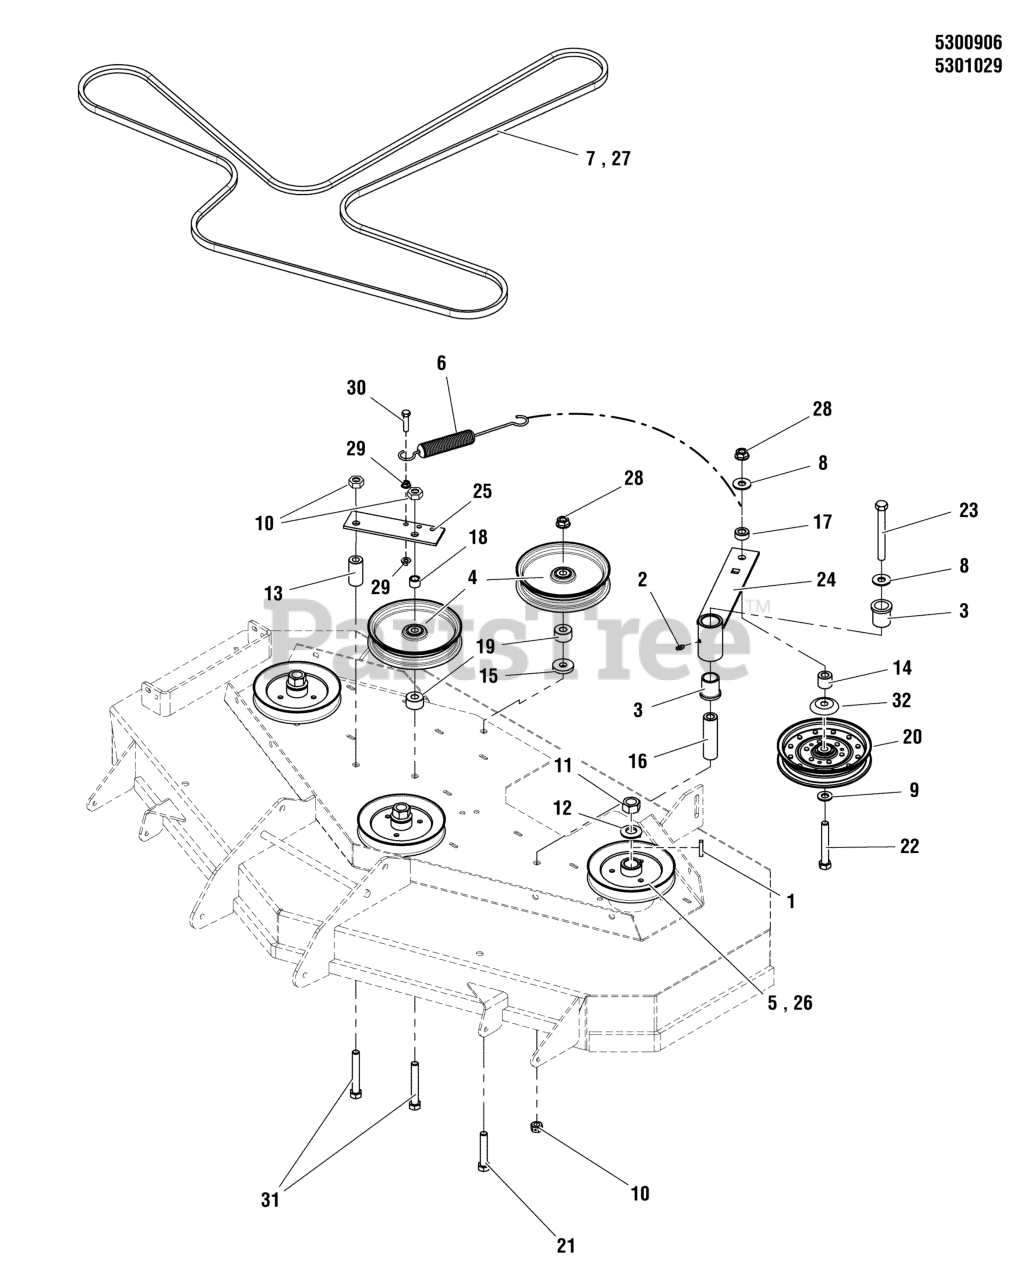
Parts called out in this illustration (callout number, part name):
1	KEY, 1/4 SQ. X 1-1/4
2	GREASE FITTING, 1/4-28 STRAIGHT
3	BUSHING, FLANGE
5	PULLEY, 6.122 OD., 52" DECK
6	SPRING, EXTENSION, SWIVEL END
7	BELT, 5V, 160.60"EL, LRG ARAMID, WRP, RC
8	WASHER, 1/2 USS
9	WASHER, 1/2 SAE
10	NUT, 1/2-13 HEX SIDE LOCK
11	NUT, 3/4-16 HEX
12	WASHER, 3/4 BELLEVILLE
13	SPACER, .50 X 1.00 X 2.00
14	SPACER, .52 X 1.00 X .88
15	WASHER, .53 X 1.50 X .25
16	SPACER, .52 X 1.00 X 3.50
17	SPACER, .52 X 1.00 X .44
18	SPACER, .51 X .75 X .56
19	SPACER, .52 X 1.25 X .70
20	PULLEY, IDLER, 6.75 OD X 1.62 FACE
21	BOLT, 1/2-13 X 2-3/4 GD5 CZ
22	BOLT, 1/2-13 X 3-1/2, HEX HD, GD5, CZ (SV)
23	BOLT, 1/2-13 X 4-1/2 GD5
24	ASSM, IDLER ARM
25	PLATE, SPRING ANCHOR - RED
26	PULLEY, 5.540OB X .985ID, SINGLE B-SEC
27	BELT, # 7-8671, 147.4
28	NUT, Hex Flange, Nylock, 1/2-13
29	NUT, 5/16-18 HEX SERRATED FLANGE (SMALL)
30	BOLT, 5/16-18 X 1-1/4 GD5 YZ
31	BOLT, 1/2-13 X 3" GD5 CZ
32	SHIELD, PULLEY BEARING
